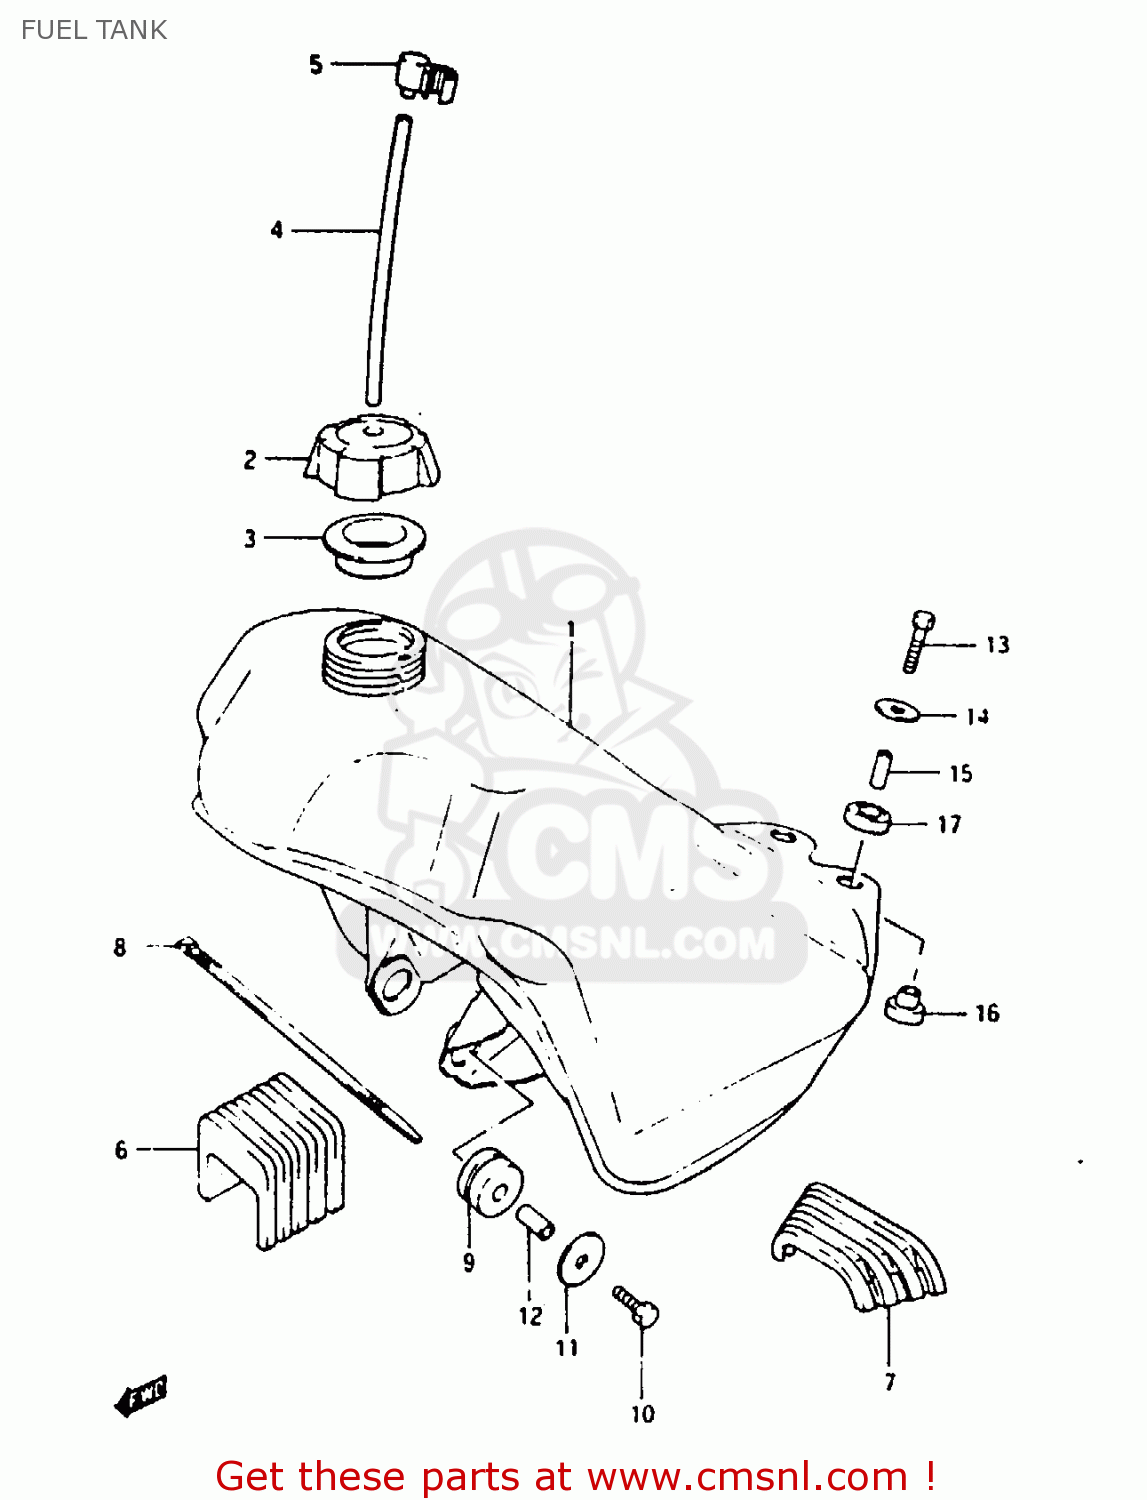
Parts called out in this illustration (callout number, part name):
1	TANK ASSY, FUEL (RED)
2	CAP SET,FUEL TANK
3	GASKET (NAS)
4	HOSE
5	CLAMP,FUEL TANK BREATHER HOSE
6	CUSHION
7	CUSHION, UPPER REAR
8	CLAMP(L:250)
9	CUSHION, FRONT
10	BOLT
11	WASHER(6.5X30X1.6)
12	SPACER (6.4X9X21.5)
13	BOLT
14	WASHER (6.5X24X1.6)
15	SPACER (6.4X9X21.5)
16	CUSHION
17	CUSHION
